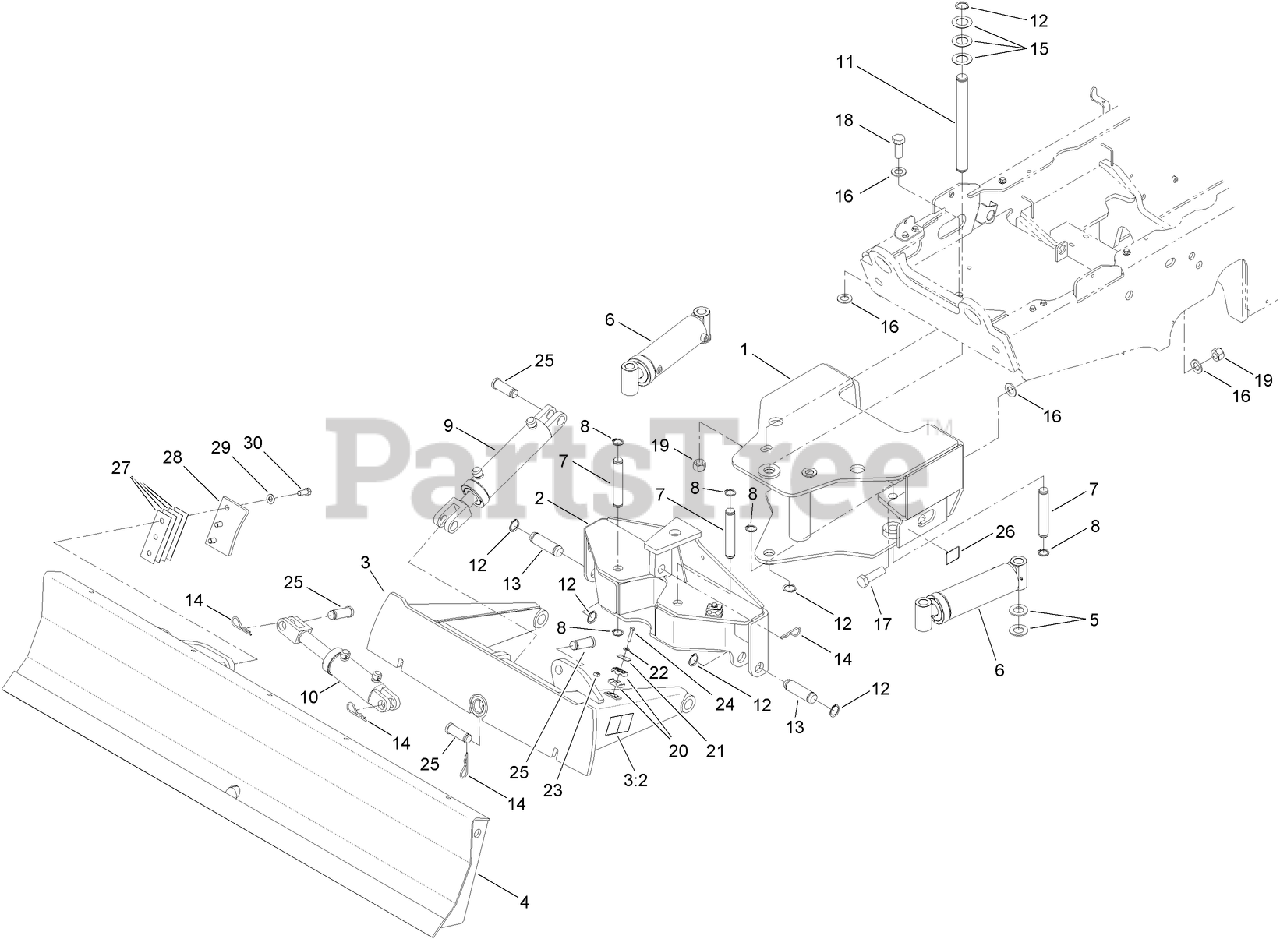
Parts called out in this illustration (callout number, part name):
1	FRAME-BLADE, BACKFILL
2	PIVOT-BLADE, BACKFILL
3	BACKFILL ARM ASM
3:2	DECAL-DANGER
4	BLADE-BACKFILL
5	WASHER-FLAT
6	HYD CYLINDER ASM
7	PIN-ANGLE, CYLINDER
8	RING-RETAINING, EXTERNAL
9	HYD CYLINDER ASM
10	HYD CYLINDER ASM
11	PIN-BLADE
13	PIN-BLADE
14	PIN-COTTER, QUICK ATTACH
17	SCREW-CAP, HH
20	CLAMP-TUBE
21	COVERPLATE
22	WASHER-HARDENED
23	NUT-SQUARE
24	SCREW-HH
25	PIN-CLEVIS
26	DECAL-TIE DOWN
27	SHIM-RETAINER
28	RETAINER-BLADE
29	WASHER-FLAT
30	SCREW-HH
